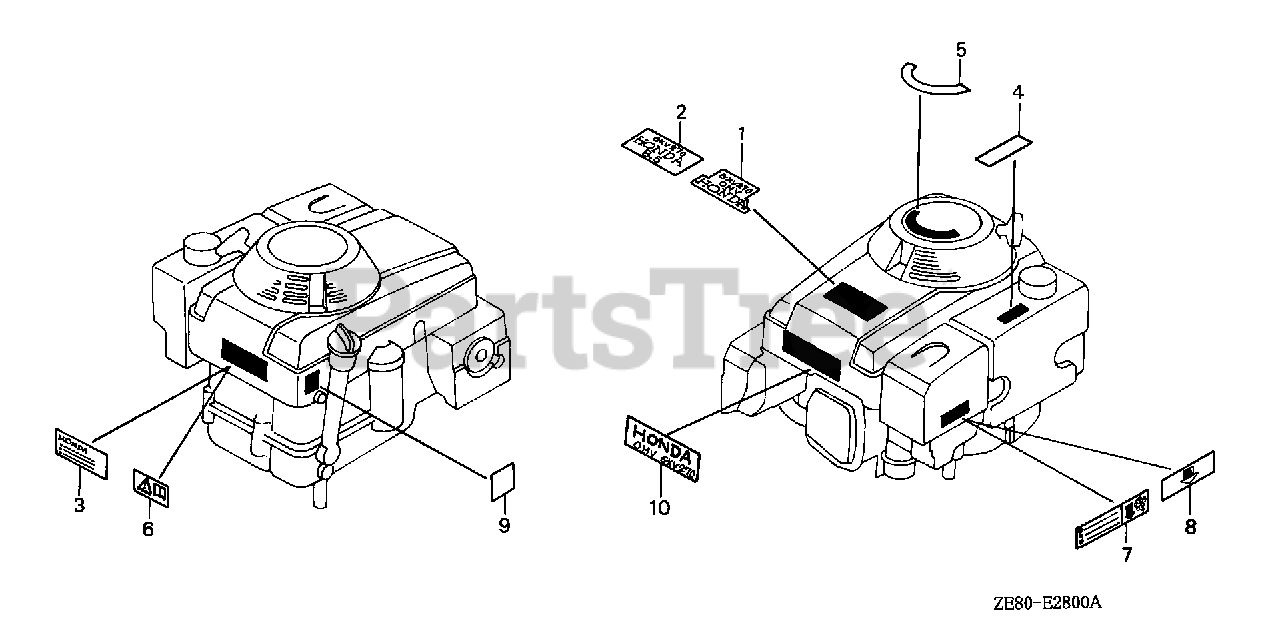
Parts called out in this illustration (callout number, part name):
1	EMBLEM, TOP COVER (E) (NOT AVAILABLE)
3	LABEL, EMBLEM (H)
4	LABEL, FUEL CAUTION (ENGLISH)
5	MARK, EASY START (ENGLISH)
7	MARK, AIR CLEANER CAUTION
9	MARK, OIL CAUTION
